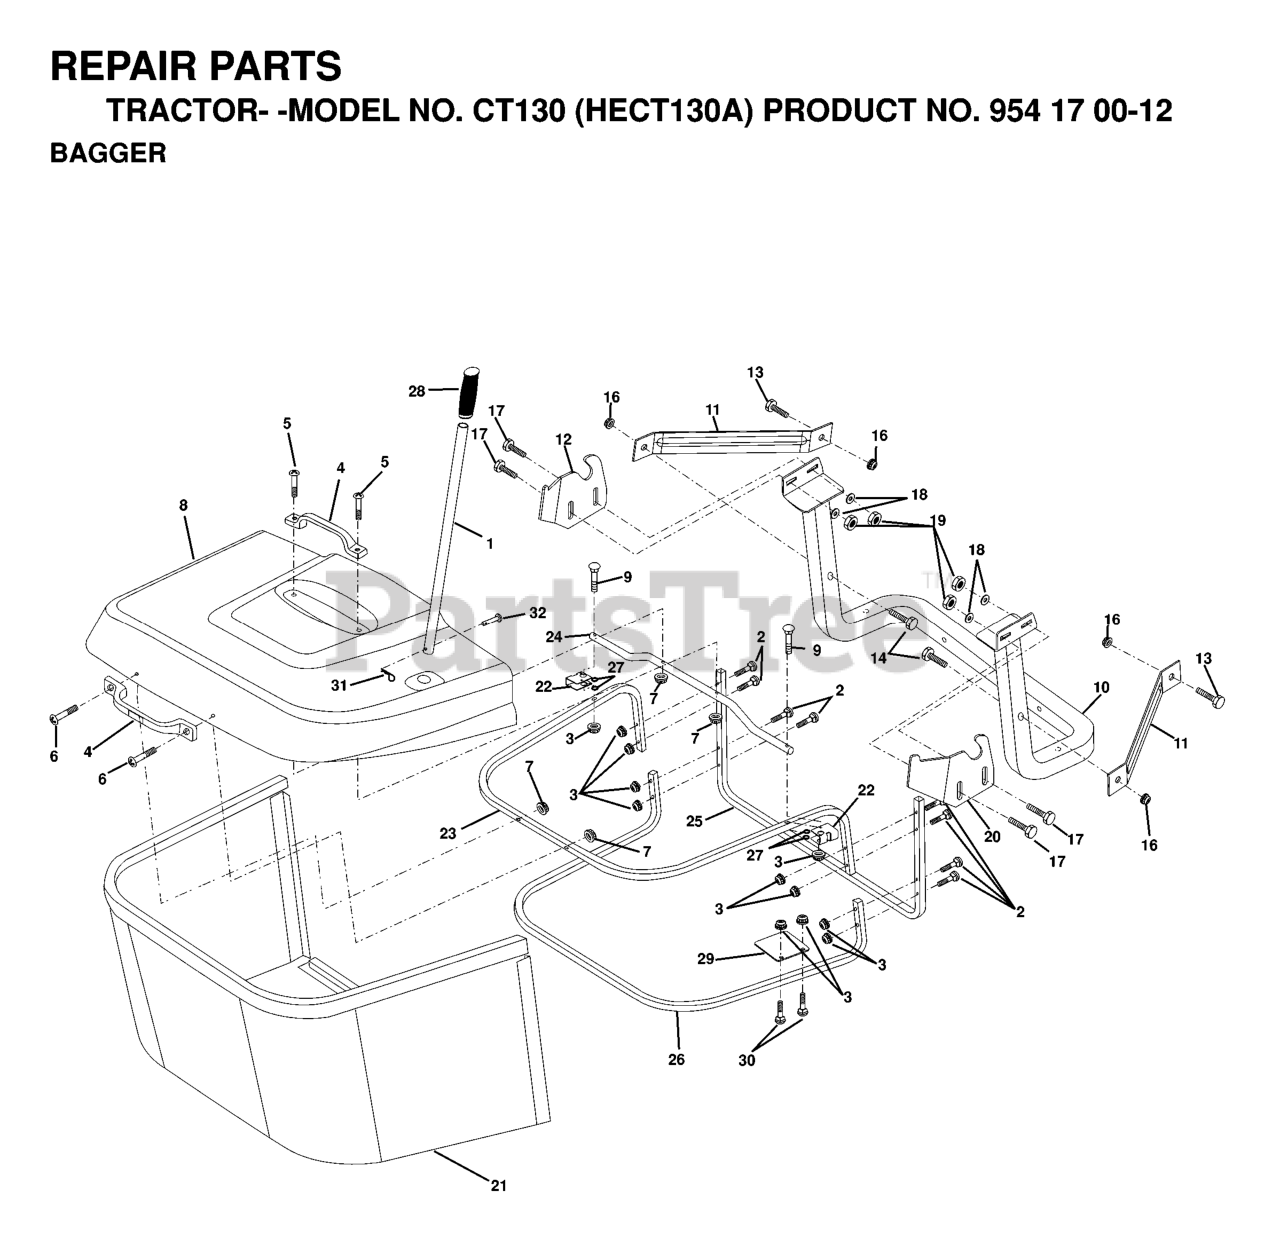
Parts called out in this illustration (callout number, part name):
1	TUBE HANDLE
2	Bolt Carriage 1/4-20 x 2.0 Gr.5
3	NUT T
5	SCREW.PAN.HEAD
6	REPL BY 532 75 00-29
7	REPL BY 873 40 10-00
8	COVER
9	Bolt Carriage 1/4-20 x 2.25d x Gr.5
11	BRACKET.SUPPORT.UPPER.BAG.CRD
14	Bolt Hex 3/8-16 x 2-1/2 Gr. 5
15	WASHER
16	NUT LOCK FLG 3/8-16 UNC
17	RP BOLT 5/16-18 X3/4 ZN/YEL GR
18	Washer 11/32 x 1-1/4 x 16 Ga.
19	NUT.71038.31-18.HEX.NYLOCK
21	BAG
22	BRKT.SIDE.BAG.CRD
23	TUBE.UPPER.BAG.CRD
24	TUBE.PIVOT.BAG.CRD.BLACK
26	TUBE.LOWER.BAG.CRD
28	GRIP.HANDLE.BLACK
30	Bolt Carriage 1/4-20 x 1 Gr.5
31	RETAINER M
32	RIVET,DRILLED
